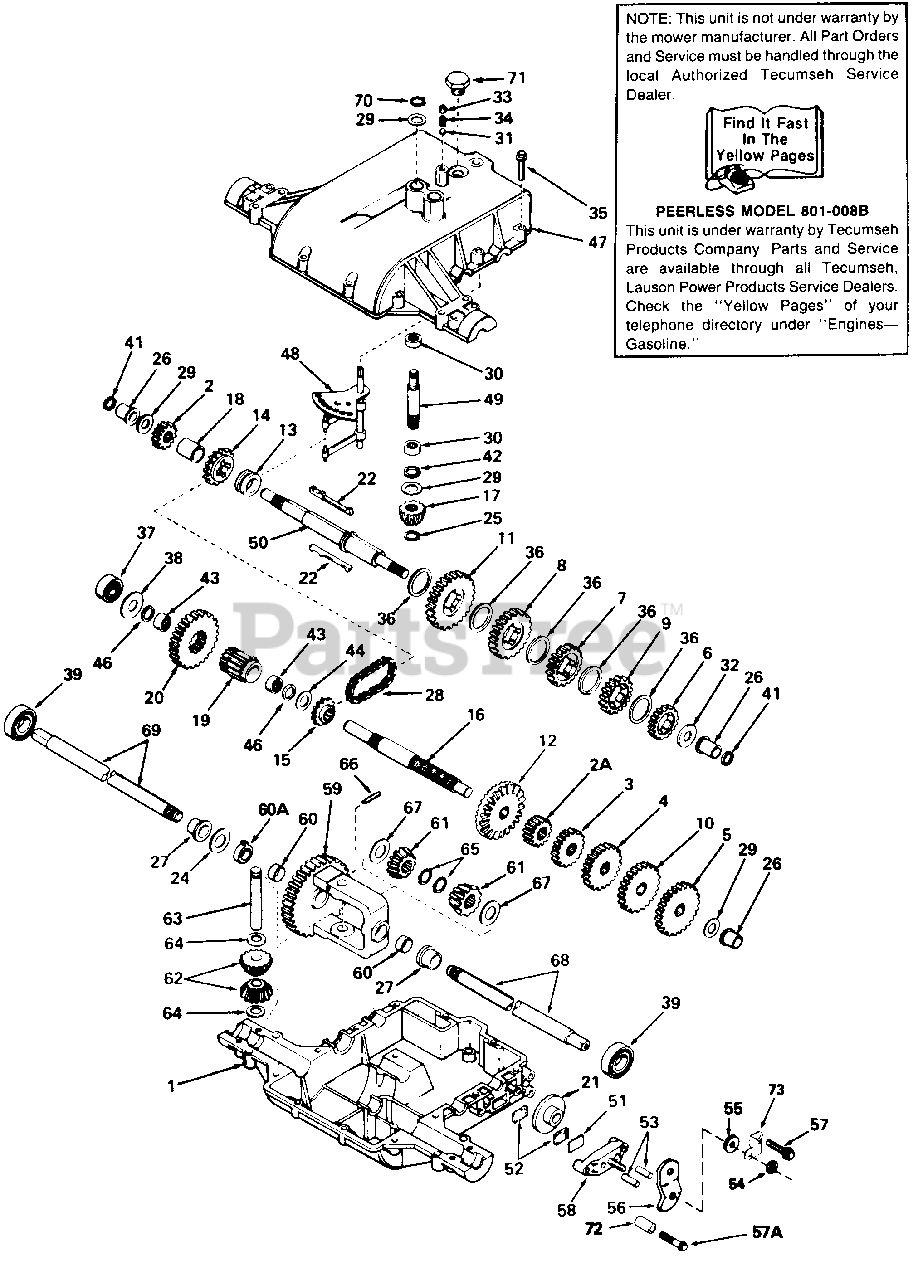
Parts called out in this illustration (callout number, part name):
1	Case, Transaxle
2	Gear, Spur (15 teeth)
2A	Gear, Spur (12 teeth)
3	Gear, Spur (20 teeth)
4	Gear, Spur (25 teeth)
5	Gear, Spur (30 teeth)
6	Gear, Spur (20 teeth)
7	Gear, Spur (25 teeth)
8	Gear, Spur (30 teeth)
9	Gear, Spur (22 teeth)
10	Gear, Spur (28 teeth)
11	Gear, Spur (37 teeth)
12	Gear, Bevel (42 teeth)
13	Collar, Shift
14	Sprocket (18 teeth)
15	Sprocket (9 teeth)
16	Shaft, Counter
17	Bevel Pinion, Input
18	Spacer
19	Pinion, Output
20	Gear, Output
21	Disk, Brake
22	Key
24	Washer
25	Ring, Retaining
26	Bushing, Flanged
27	Bushing, Flanged
28	Chain, Roller (No. 41 Chain, 24 Links)
29	Washer, Thrust
30	Bearing, Needle
31	Ball, Steel
32	Washer, Thrust
33	Screw, Set, 3/8-16 x 3/8
34	Spring
35	Screw, Hex Hd. Thread Forming, 1/4-20 x 1-1/4
36	Washer, Thrust
37	Bearing, Ball
38	Washer, Flat
39	Bearing, Ball
41	Ring, Square Cut
42	Ring, Square Cut
43	Bearing, Needle
44	Washer, Flat
46	Ring, Square Cut
47	Cover, Transaxle
48	Rod & Fork Ass'y., Shift
49	Shaft, Input
50	Shaft, Brake
51	Plate, Brake Pad
52	Pad, Brake
53	Pin, Dowel
54	Locknut, 5/16-24
55	Washer, Flat
56	Lever, Brake
57	Screw, Hex Hd. Thread Forming, 1/4-20 x 1-1/4
57A	Screw, Hex Hd. Thread Forming, 1/4-20 x 2-1/4
58	Holder, Brake Pad
59	Gear Ass'y., Differential
60	Bushing
60A	Bushing
61	Gear, Bevel
62	Pinion, Bevel
63	Pin, Drive
64	Washer, Thrust
65	Ring, Retaining
66	Pin, Roll
67	Washer, Thrust
68	Axle (15-1/4" Long)
69	Axle (13-3/8" Long)
70	Ring, Retaining
71	Plug, Hex Hd., 9/16-18 Thread
72	Spacer
73	Bracket, Brake Lever
